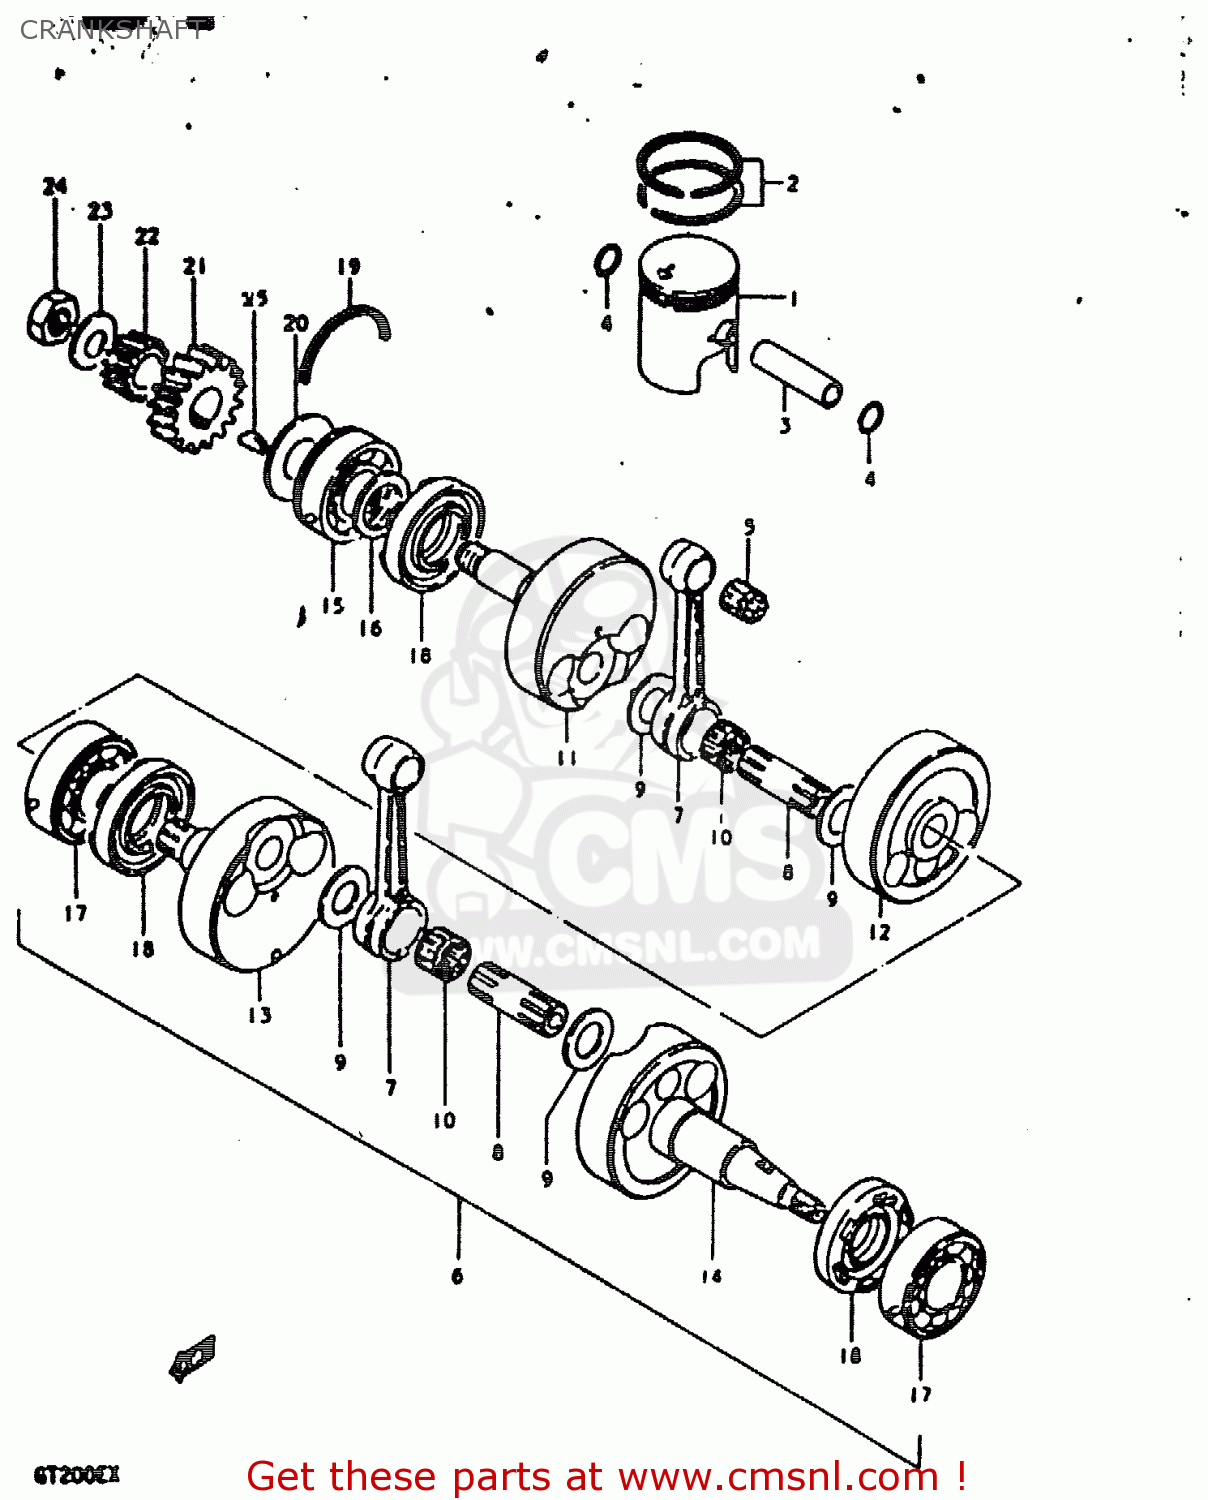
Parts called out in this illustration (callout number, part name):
1	PISTON
2	RING SET,PISTON
3	PIN,PISTON 14MM
4	RING,SNAP 14MM
5	BEARING
6	CRANKSHAFT ASSY
7	CONNECTING ROD
8	PIN,CRANK
9	WASHER(19X32X1)
10	BEARING(19X25X16)
11	CRANKSHAFT, RH
12	WEB, CRANK
13	CRANKSHAFT, MIDDLE
14	CRANKSHAFT, LH
15	BEARING(25X62X17)
16	WASHER
17	BEARING
18	SEAL,OIL(30X62X11)
19	C RING
20	WASHER(20X48X1)
21	GEAR, PRIMARY DRIVE
22	GEAR, TACHOMETER DRIVE NO.1
23	WASHER
24	NUT
25	KEY
